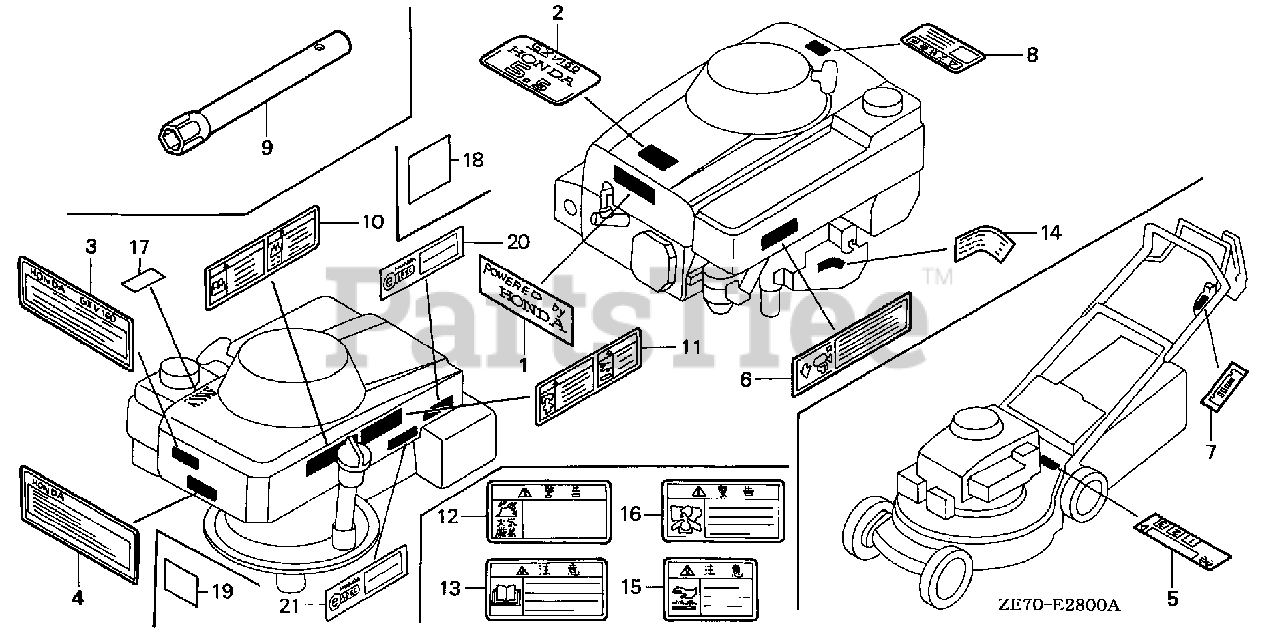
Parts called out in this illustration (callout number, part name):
1	EMBLEM, TOP COVER (E)
4	MARK, CAUTION (H)
5	MARK, BRAKE CAUTION
6	LABEL, AIR CLEANER CAUTION (H)
9	WRENCH, BOX (P21)
14	MARK, CONTROL
17	LABEL, FUEL CAUTION
